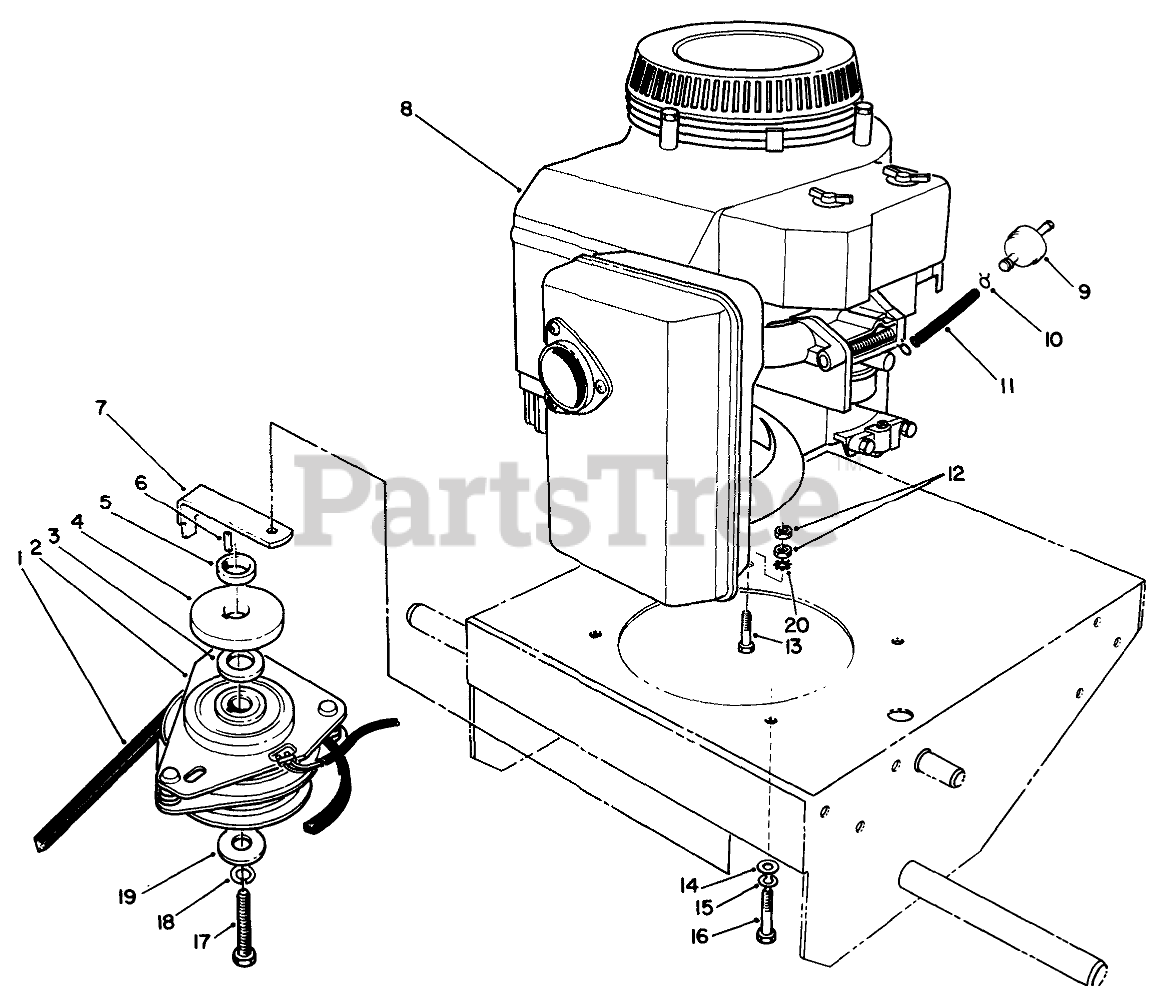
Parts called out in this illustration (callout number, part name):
1	V-BELT, DRIVE
2	CLUTCH/BRAKE
3	SPACER-LOWER
4	Pulley-Drive
5	Spacer-Upper
6	KEY-SQUARE
7	Retainer-Clutch
9	FILTER-FUEL
10	CLAMP-HOSE
11	HOSE-FUEL
12	NUT-JAM
13	SCREW (ENGINE, GROUND)
14	WASHER-PLAIN
15	WASHER-LOCK
16	SCREW-HH
17	SCREW-CLUTCH
18	WASHER-LOCK
19	WASHER-CLUTCH
20	WASHER-LOCK
